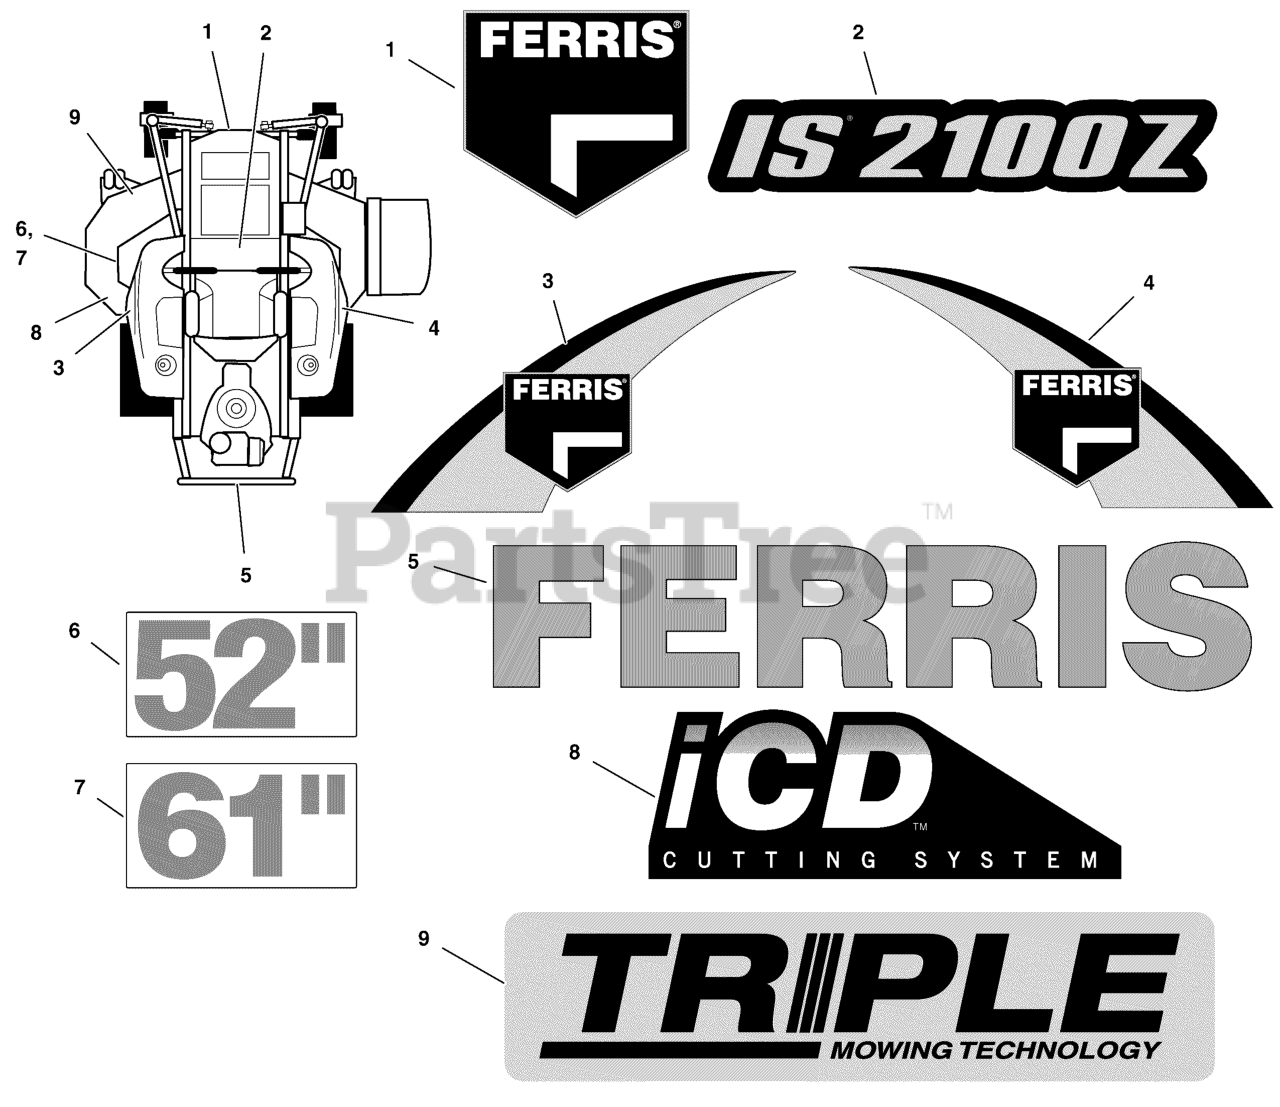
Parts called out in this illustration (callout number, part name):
1	DECAL, BRAND
2	DECAL, MODEL
3	DECAL, Model, Left Hand
4	DECAL, Model, Right Hand
5	DECAL, FERRIS, 2.23" X 11.39"
6	DECAL, 52
7	DECAL, 61"
8	DECAL, iCD CUTTING SYSTEM
9	DECAL, TRIPLE MOWING TECHNOLOGY
